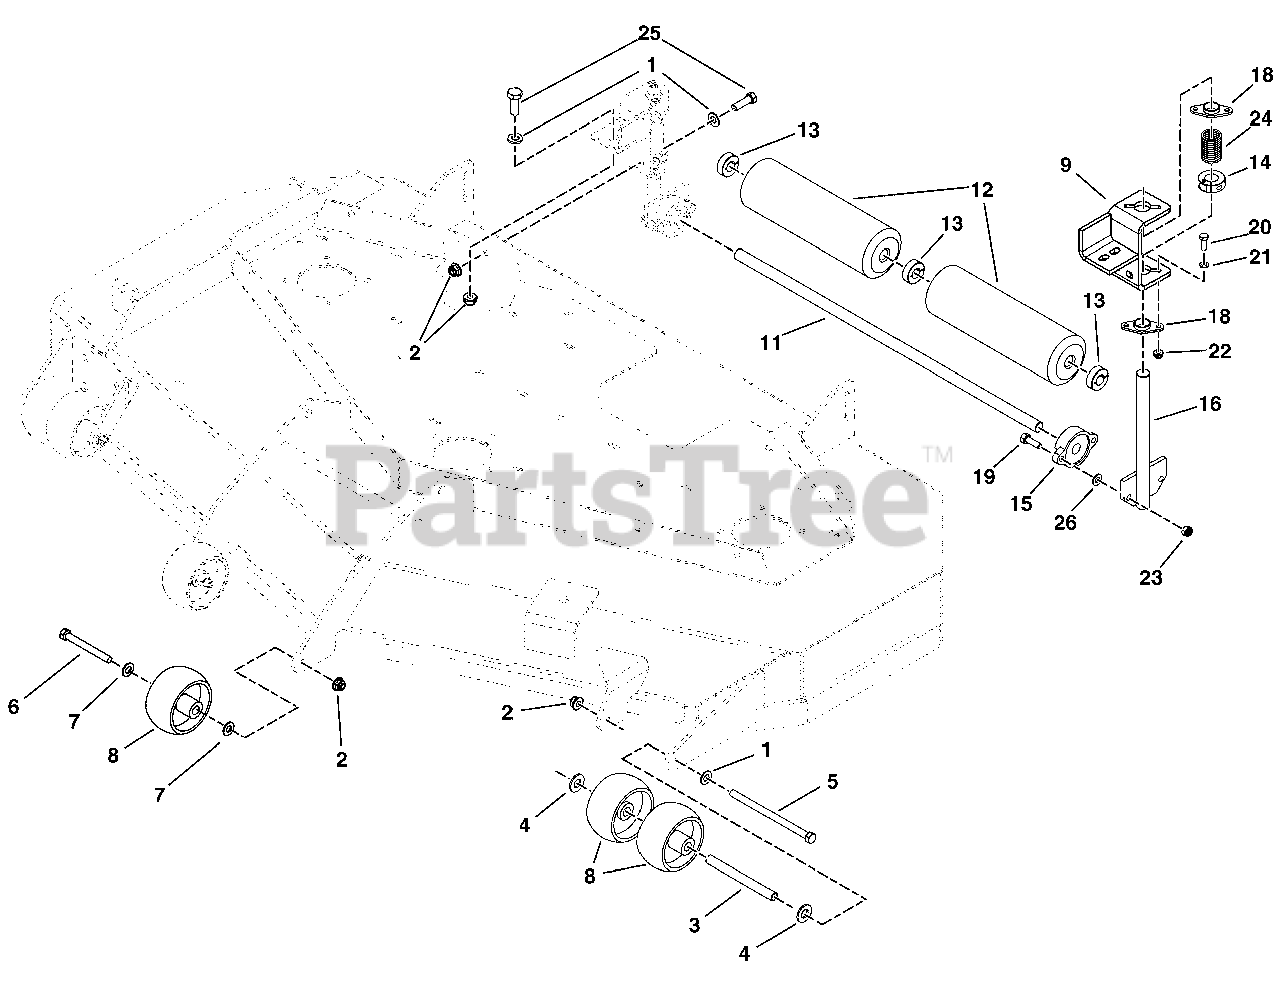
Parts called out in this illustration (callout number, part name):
1	WASHER, 3/8 SAE
2	NUT, 3/8-16 Hex Nylock Flange
3	SPACER, .38 X .50 X 5.06
4	WASHER, 1/2 SAE
5	BOLT, 3/8-16 X 6"
6	BOLT, REAR WHEEL
7	WASHER-0500(0.51IDX0.87ODX.06THK) BLK
8	GAUGE WHEEL
9	STRIPER MOUNT, LH
11	SHAFT, Roller
12	ROLLER
13	COLLAR, 5/8" Split
14	COLLAR, 3/4" Double Split
15	BEARING, Flange
16	GUIDE SHAFT, LH
18	BUSHING, Flange
19	BOLT, 5/16-18 X 1" GD
20	BOLT, 1/4-20 X 3/4"
21	WASHER, 1/4 SAE (5025154)
22	NUT, 1/4-20 HEX NYLOCK FLANGE (5025391)
23	NUT, 5/16-18 HEX NYLO
24	SPRING, Compression
25	BOLT, 3/8-16 X 1-1/4"
26	WASHER, 5/16" SAE
